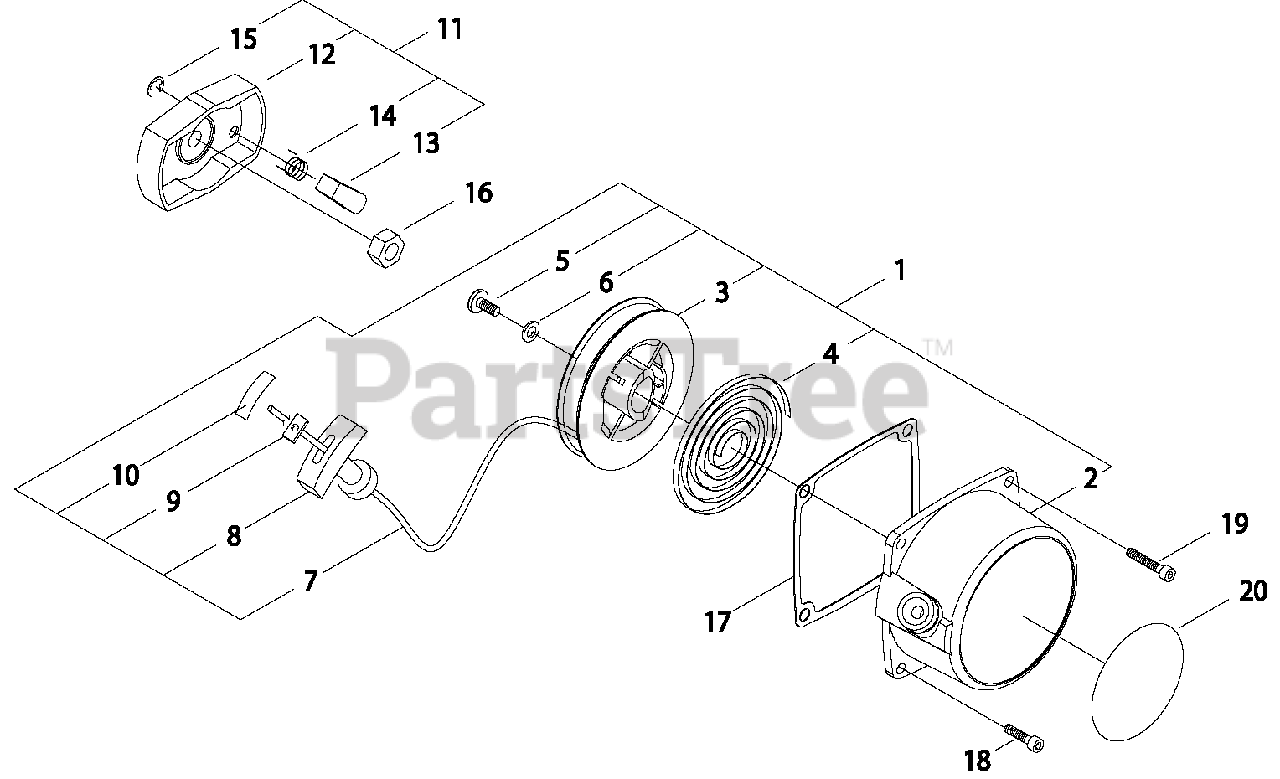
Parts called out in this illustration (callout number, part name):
1	STARTER ASSY
2	CASE, STARTER
3	REEL, ROPE
4	SPRING, REWIND
5	SCREW - 5
6	WASHER
7	ROPE, STARTER
8	GRIP, STARTER
9	RETAINER, ROPE
10	TAPE, ADHESIVE
11	STARTER PAWL ASSY
12	REEL, ROPE
13	PAWL, STARTER
14	SPRING, RETURN
15	RING, RETAINING
16	NUT - 8
17	GASKET, STARTER
18	SCREW - 4X16
19	SCREW - 4X10
20	LABEL - MODEL
